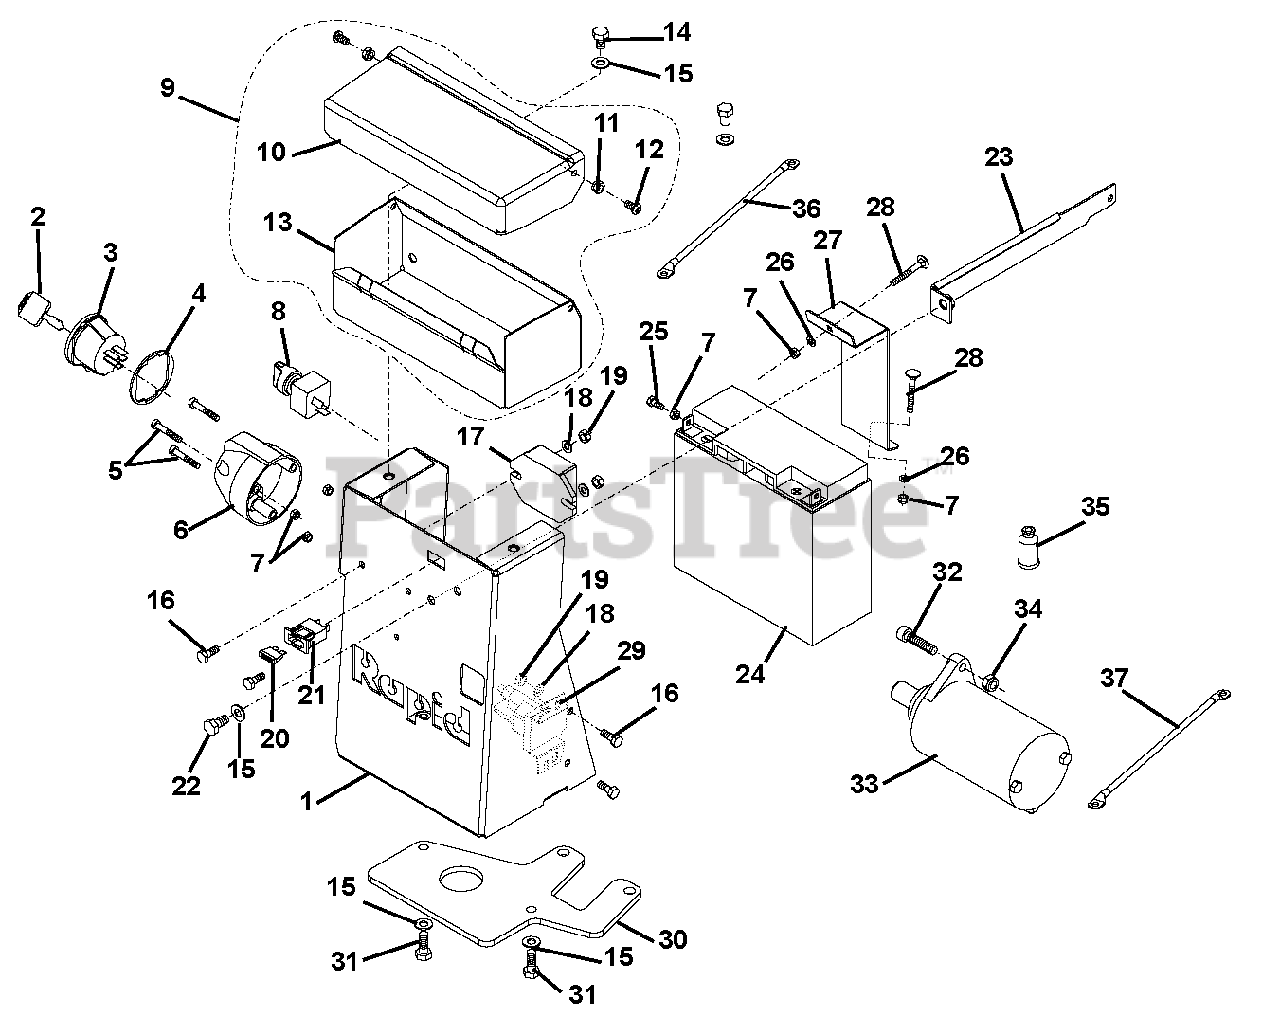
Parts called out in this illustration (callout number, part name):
1	Battery Container
2	Assembly, Key
3	Assembly, Starter Switch
4	Spacer
5	Screw, Cylindrical Head
6	Plug, Socket
7	Nut, Lock M5
8	Switch, Rotary
9	Tool Box Assembly, (Includes 10 - 13)
11	Nut, Lock D985 M6
12	Screw, M6 x 12
13	Box, Tool
14	Bolt, Hex D933 M8 x 12
15	Washer, M8
16	Bolt, Hex M6 x 16
17	Regulator
19	Nut, Hex M6
20	15A, Fuse
21	Fuse Box
22	Bolt, Hex M8 x 16
24	Battery, RapidES 17-12 (12V 17AH) L 7.13 x W 2.99 x H 6.58
25	Bolt, D933 M5 x 12
26	Washer, 5.3 x 10 x 1
27	Bow, Fastener
28	Screw, Truss Head, D603 M5 x 40
30	Support, Battery
31	Bolt, Hex M8 x 20
32	Screw, Cylindrical Head
33	Electrical Starter
34	Nut, Lock M8
35	Protecting Cap
36	Cable, Black
37	Cable, Red
